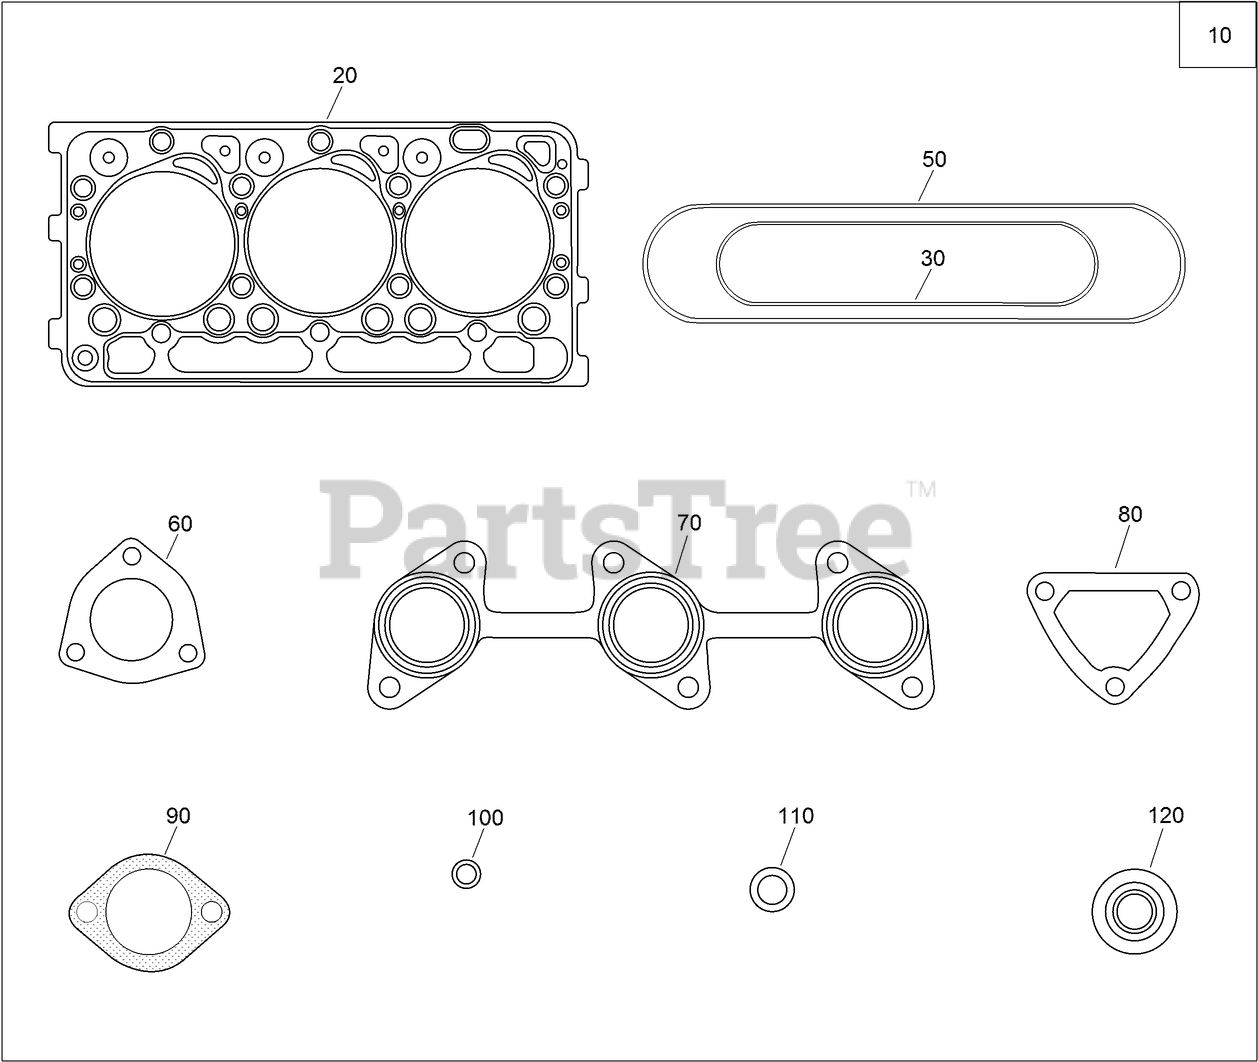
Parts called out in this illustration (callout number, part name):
10	UPPER GASKET KIT
20	GASKET-HEAD, CYLINDER
30	GASKET-COVER, HEAD
50	GASKET-MANIFOLD, INTAKE
60	GASKET-MUFFLER
70	GASKET-MANIFOLD, EXHAUST
80	GASKET-FLANGE, WATER
90	GASKET-THERMOSTAT
100	O-RING
110	GASKET
120	SEAL-STEM, VALVE
